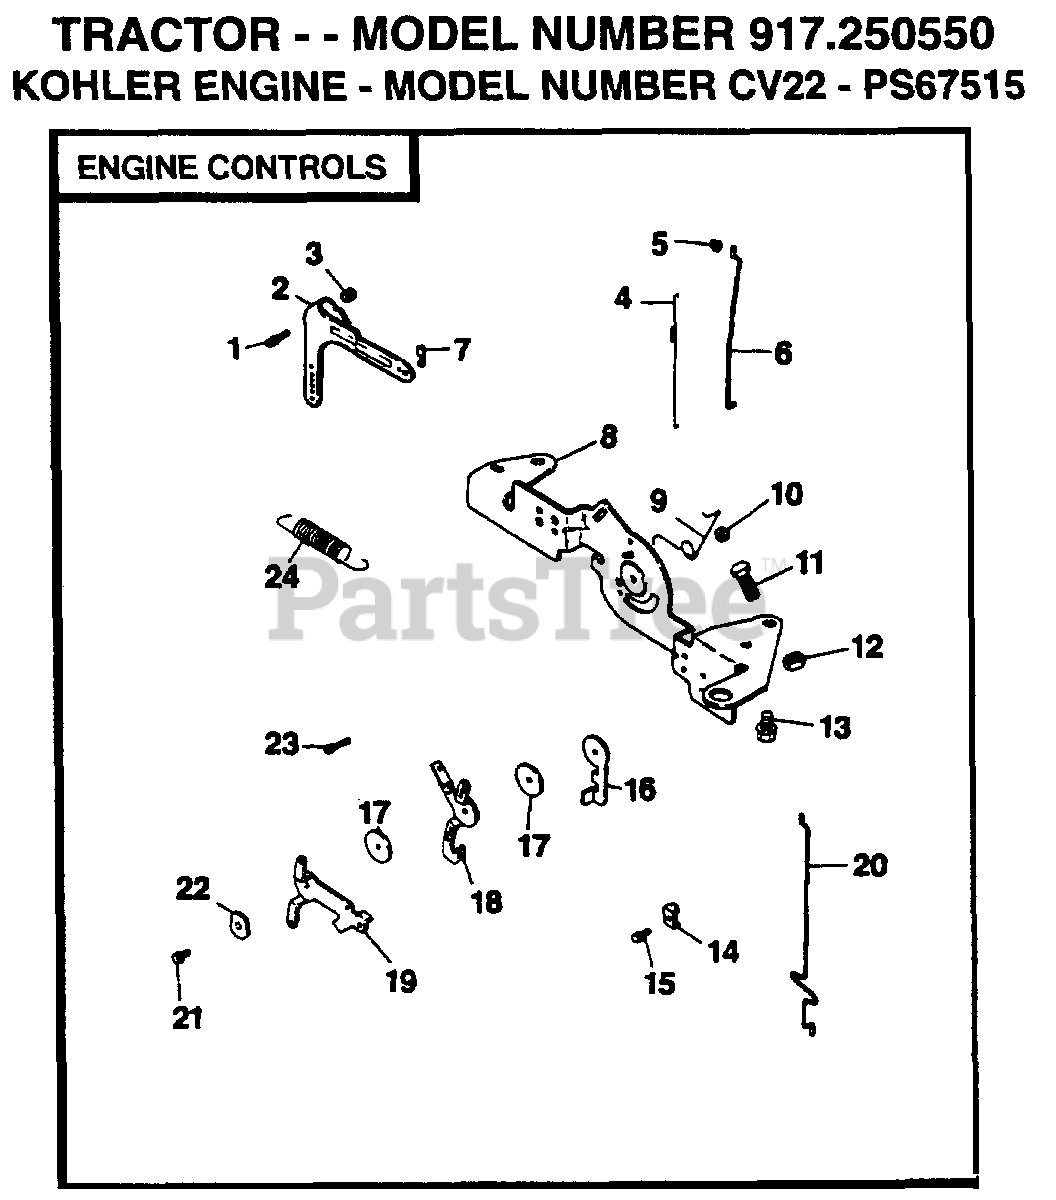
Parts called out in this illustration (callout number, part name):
1	SCREW, GOVERNOR ARM
3	NUT, GOVERNOR ARM
11	SCREW, CABLE CLAMP
13	SCREW, HEX HEAD
15	SCREW, CABLE CLAMP
